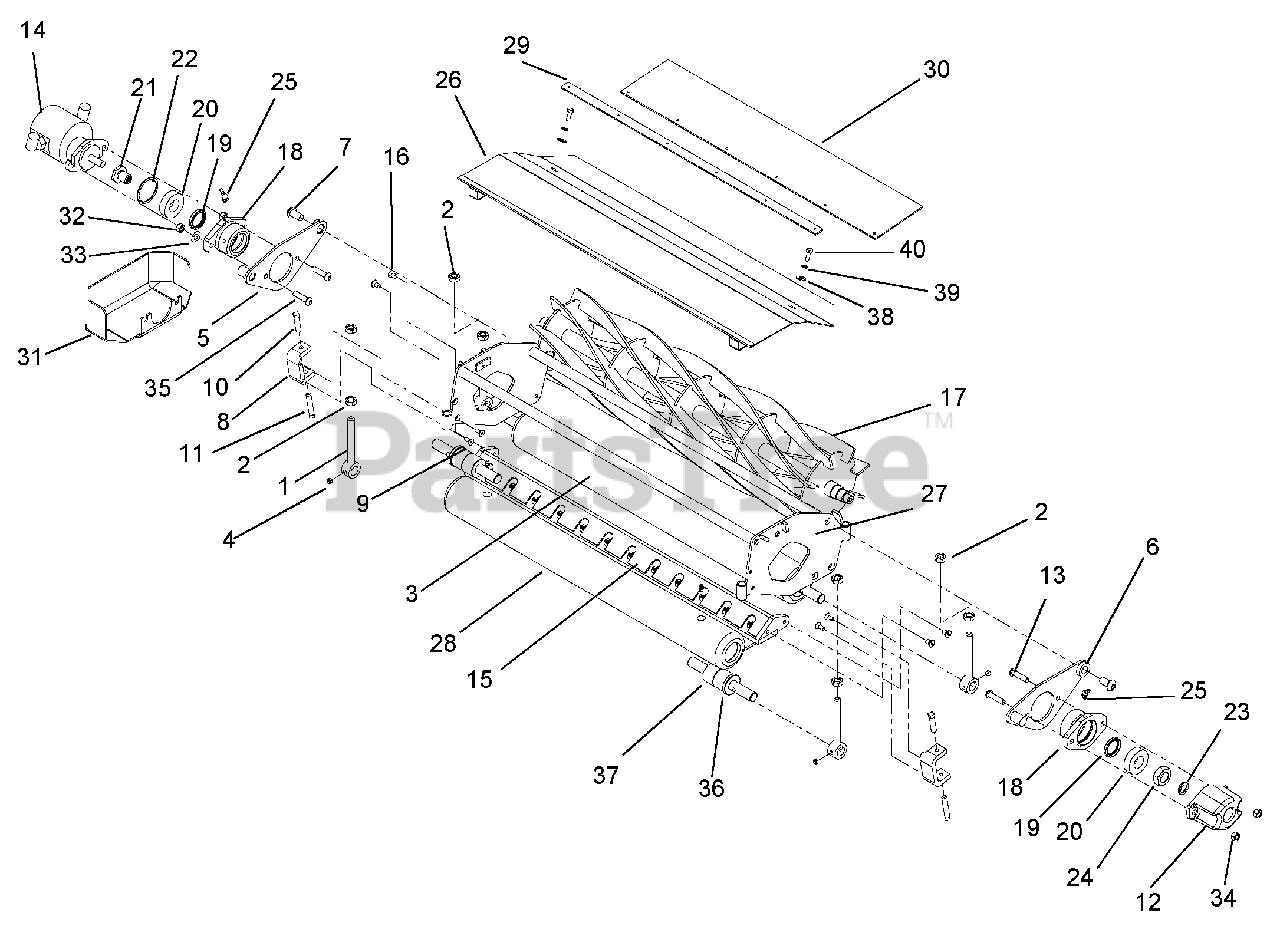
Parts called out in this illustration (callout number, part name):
1	ROLLER ADJUSTER WELDMENT
2	JAM NUT 1/2-13 CP
3	ROLLER ASSEMBLY SMOOTH ALUMINUM 3.00
4	SETSCREW HEX SOC HD 3/8-16 X 1/4
5	BEARING HOUSING ADAPTER WLDMNT, RH (7" UNIT)
6	BEARING HOUSING ADAPTER WELDMENT, LH (7" UNIT)
7	SHOULDER BOLT 5/8 X 1/2 X 12-13 SS
8	STANDARD ADJUSTER BRACKET
9	HEX SOC FLT CSK HD CPSC 1/4-28 X 5/8
10	SQ HD SET SCREW, 3/8-16 X 1-1/2
11	SQ HD SET SCREW, 3/8-16 X 2
12	COUNTERWEIGHT REEL HOUSING, MACHINED
13	BUTTON HEAD CAP SCREW 3/8-16 X 1-1/2
14	MOTOR, HYDRAULIC
15	BEDBAR ASSEMBLY, 30" PR-3084 (INCLUDES THE FOLLOWING ITEMS)
16	HEX SOC FLT CSK HD CPSC 5/16-18 X 5/8
17	8 BLADE REEL WELDMENT
18	MODIFIED BEARING HOUSING
19	SEAL, OIL 1.565 OD X 1.125 ID
21	SPLINED NUT
22	SPIROLOCK RETAINING RING
23	SEAL, OIL 1.004 OD X .625 ID X .125
24	JAM NUT 7/8-14 NYLOCK
25	45 DEGREE GREASE FITTING 1/4-28
26	30" REEL SHIELD
27	CUTTING UNIT FRAME
28	ROLLER TUBE
29	STRAP, RUBBER FLAP
30	RUBBER FLAP
31	GUARD, MOTOR
32	NYLOCK NUT 3/8-16
33	3/8 SAE FLATWASHER
34	SERATED FLANGE NUT 3/8-16
35	BUTTON HD CPSC 3/8-16 X 1-3/4 SS
36	GREASE SEAL
38	1/4" USS FLATWASHER
39	1/4" LOCKWASHER
40	HHCS 1/4-20 X 3/4"
